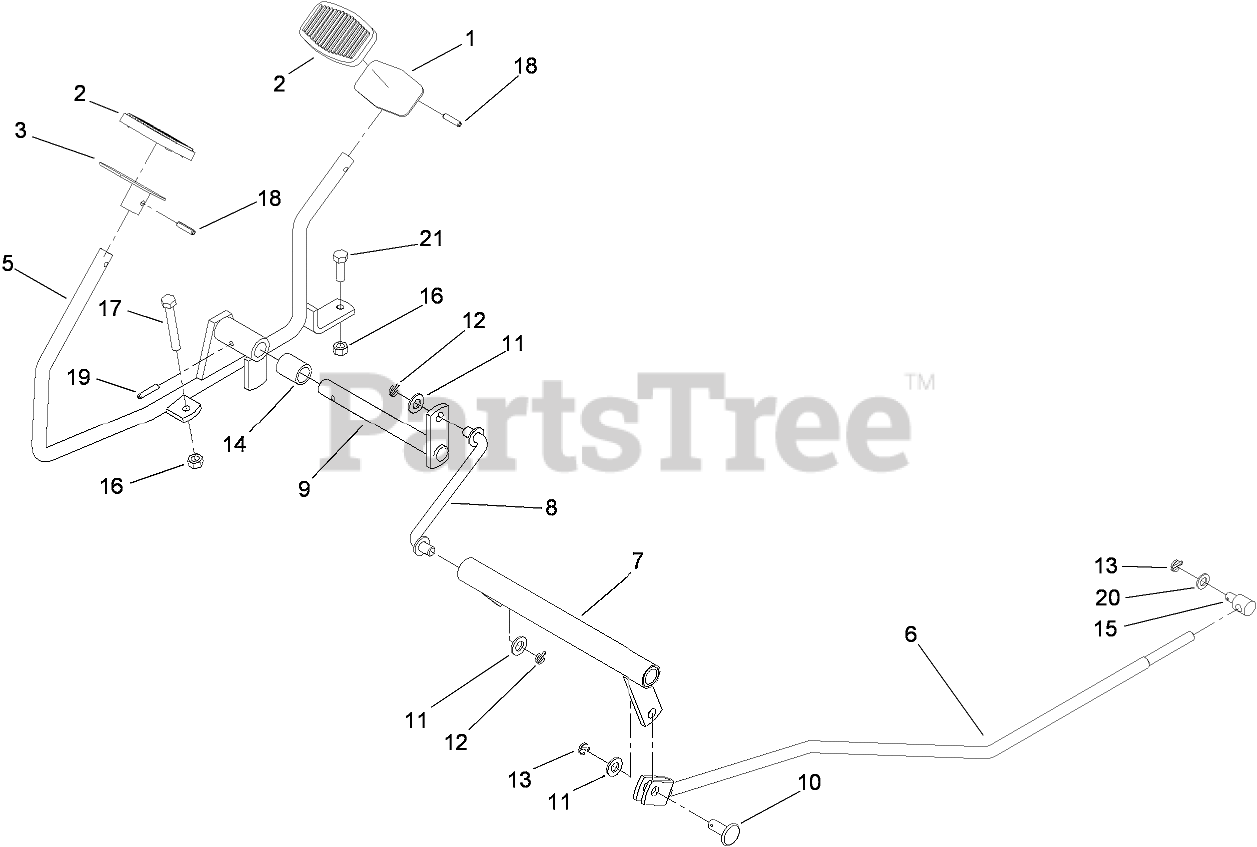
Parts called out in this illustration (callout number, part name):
1	PEDAL-REAR, TRAVEL
2	PAD-PEDAL
3	PEDAL-TRAVEL, FORWARD
5	ROD-TRAVEL
6	ROD-TIE
7	SHAFT-DIAGONAL
8	LINK-FORMED
9	SHAFT-DIAGONAL
11	WASHER-FLAT
12	PIN-COTTER
13	PIN-COTTER
14	SPACER
16	NUT-HEX
17	SCREW-HH
18	PIN-SPRING
19	PIN-SPRING
20	WASHER
21	SCREW-HH
